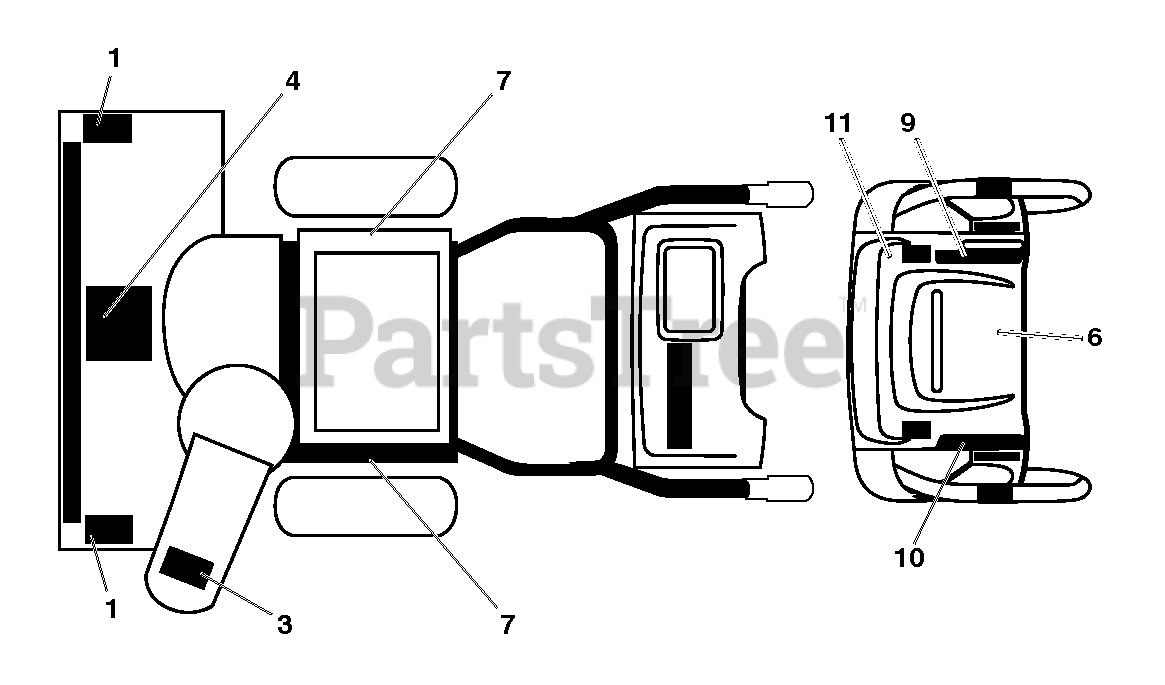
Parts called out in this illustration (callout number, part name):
1	DECAL.AUGER.SAFETY.
3	DECAL.CHUTE.SAFETY.EU/SC.17
4	DECAL.AUGER."
7	DECAL.BELT.GUARD.
9	DECAL CONSOLE DECAL DECAL.SNOW
10	DECAL CONSOLE DECAL DECAL.SNOW
11	DECAL.CONSOLE.HAND.WARMER
